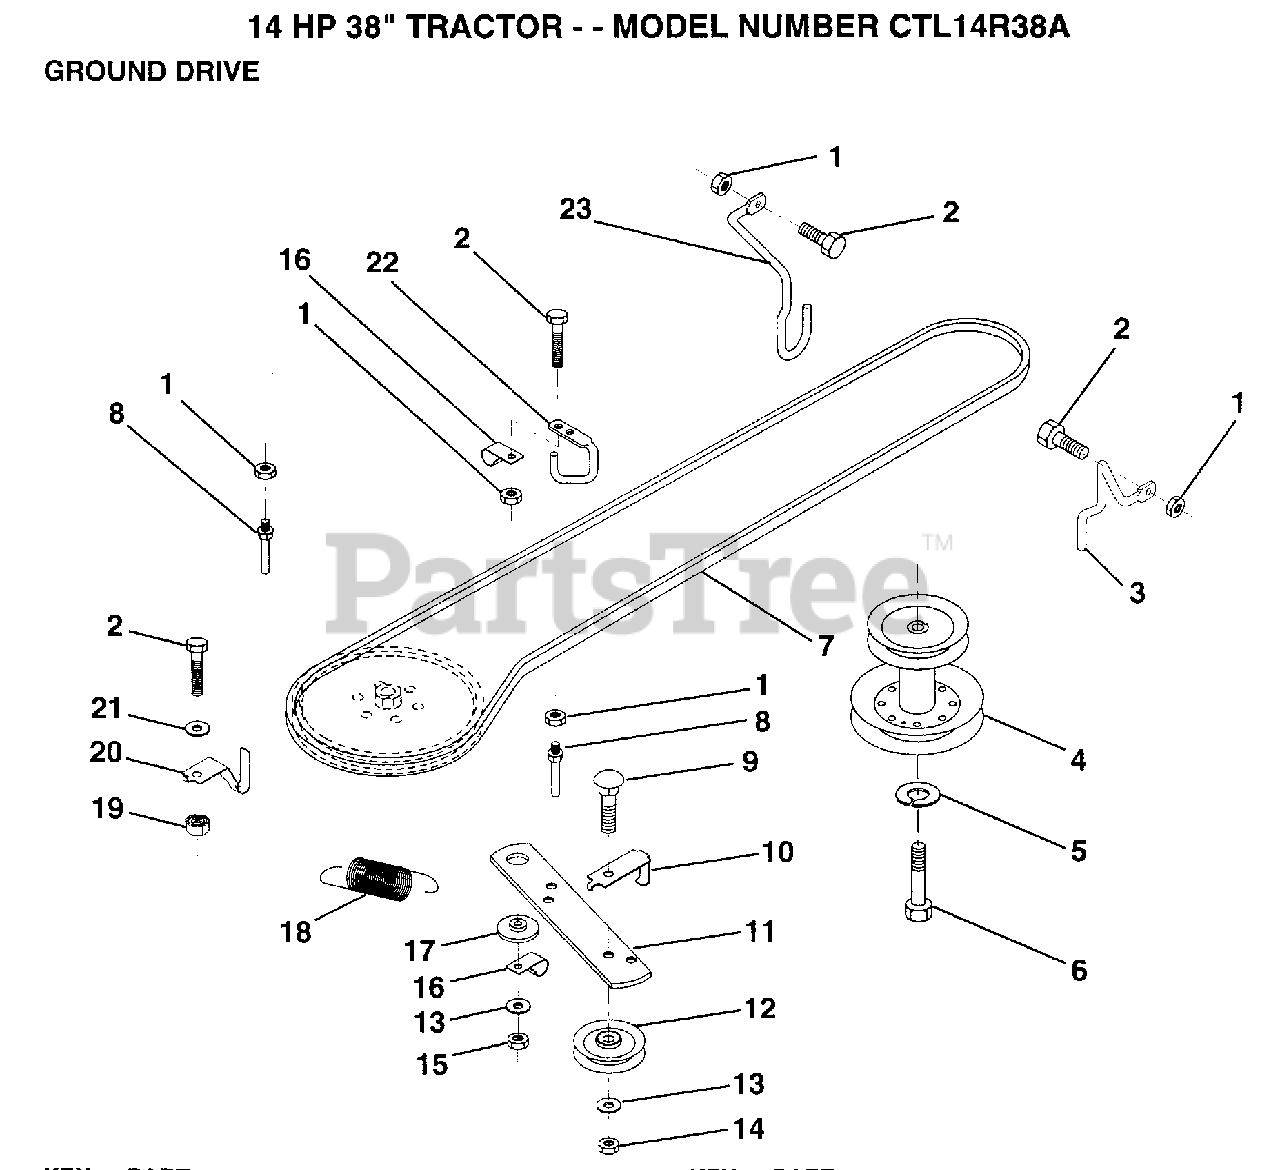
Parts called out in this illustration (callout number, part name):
1	NUT
2	BOLT
3	KEEPER.BELT.FRT.
4	PULLEY.ENGINE.LR
5	LOCKWASHER
6	HEX BOLT
7	BELT
8	"KEEPER,DRIVE BELT"
9	BOLT
10	"KEEP,IDLER DR BEL"
11	ARM IDLER CLUT GD
12	PULLEY.IDLER.FLAT
13	WASHER
14	LOCKNUT
15	NUT
16	CLIP INSULATOR
17	SPACER RETAINER
20	"KEEPER,DR BELT "
21	WASHER
22	"KEEPER,FRA DR BEL"
23	KEEPER.BELT.FRT.L
